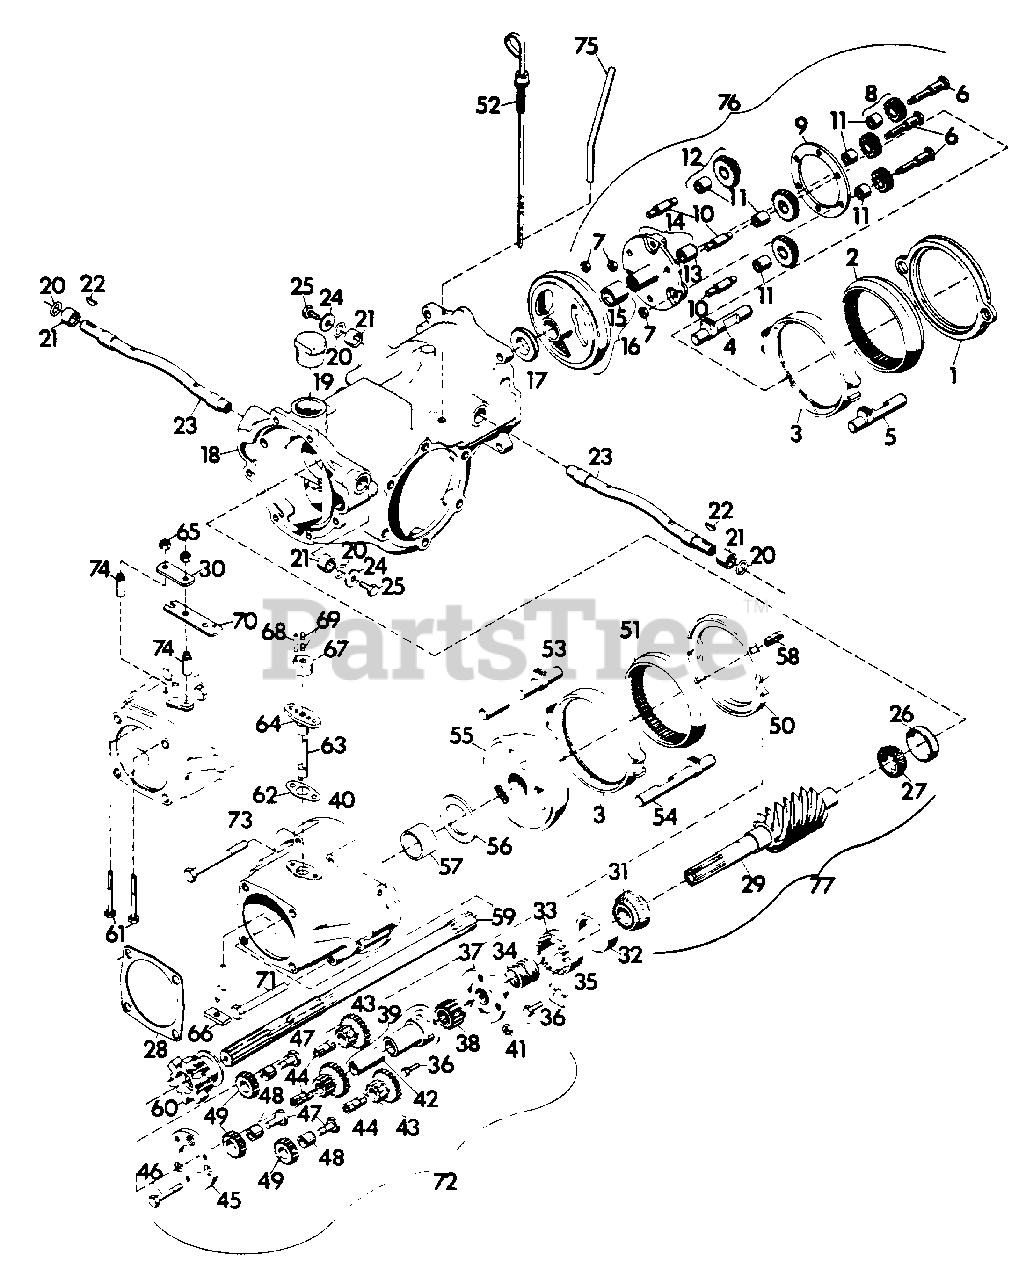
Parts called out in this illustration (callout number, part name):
1	SPACER, REAR
2	GEAR, REAR RING
3	ASSEMBLY, CLUTCH CUP
4	ROD, REAR CLUTCH SLIDE L.H.
5	ROD, REAR CLUTCH SLIDE R.H.
6	BOLT, ORBIT GEAR
7	NUT, LOCK 5/16-18 L.H. THD.
8	ASSEMBLY, EXTERNAL ORBIT GEAR
9	SPACER, PIN
10	PIN, HI-LO ORBIT GEAR
11	BUSHING, .501X.627X.495
12	ASSEMBLY, INTERNAL ORBIT GEAR
13	BUSHING, .737X.877X.682
14	ASSEMBLY, PLANET GEAR CARRIER
15	BUSHING, 1.231X1.502X1.312
16	ASSEMBLY, RING GEAR AND BUSHING
17	PLATE, REAR THRUST
18	CHASSIS
19	PLUG, OIL FILLER
20	O-RING, .750X1.00
21	BUSHING, .750X1.002X.625
22	KEY, WOODRUFF .125X.625 HARD
23	SHAFT, ACTUATING
24	WASHER, FLAT .265X1.250X.063
25	BOLT, HEX 1/4-20X.50
26	CUP, ROLLER BEARING
27	CONE, ROLLER BEARING
28	GASKET, ATTACHMENT
29	WELDMENT, 8-LEAD WORM
30	SPACER, STRAP
31	CONE, ROLLER BEARING
32	CUP, ROLLER BEARING
33	NUT, BEARING ADJUSTMENT
34	SPACER, SPRING PIN PLATE
35	NUT, ADJUSTING
36	BOLT, HEX 1/4-20X.625
37	PLATE, FRONT PIN
38	GEAR, SUN PINION
39	ASSEMBLY, QUILL AND BUSHING
40	ASSEMBLY, ADVANCE CASTING
41	NUT, HEX 1/4-20
42	BUSHING, .875X1.000X2
43	GEAR, ORBIT SPUR
44	PIN, FWD-REV ORBIT GEAR
45	SPACER, FRONT PIN
46	BOLT, SPACER
47	BOLT, REVERSE IDLER
48	BUSHING, REVERSE IDLER
49	GEAR, REVERSE IDLER SPUR
50	CUP, GEAR
51	GEAR, INTERNAL SPUR
52	ASSEMBLY, DIPSTICK
53	ROD, CLUTCH SLIDE L.H.
54	ROD, CLUTCH SLIDE R.H.
55	CONE, REVERSE GEAR
56	DISC, FRICTION
57	BEARING
58	PIN, ROLL
59	SHAFT, PINION
60	DOG, ATTACHMENT
61	BOLT, HEX 5/16-18X2.25
62	GASKET, SHIPPER SHAFT
63	SHAFT, SHIPPER
64	GUIDE, SHIPPER SHAFT
65	NUT, LOCK 5/16-18
66	BLOCK TRUNNION
67	BODY, SHIPPER SHAFT
68	PIN, SPRING .25X.75
69	SCREW, SET 3/8-16X.25
70	ARM, SHIFTER
71	BOLT, HEX 5/16-18X3.50 GR. 8
72	ASSEMBLY, FWD-REV PLANETARY
73	BOLT, HEX 5/16-18X3.25 GR. 8
74	SPACER, SHIPPER SHAFT GUIDE
75	GUIDE, DIPSTICK
76	ASSEMBLY, HI-LO PLANETARY
77	ASSEMBLY, WELDED WORM SHAFT-8 LEAD
